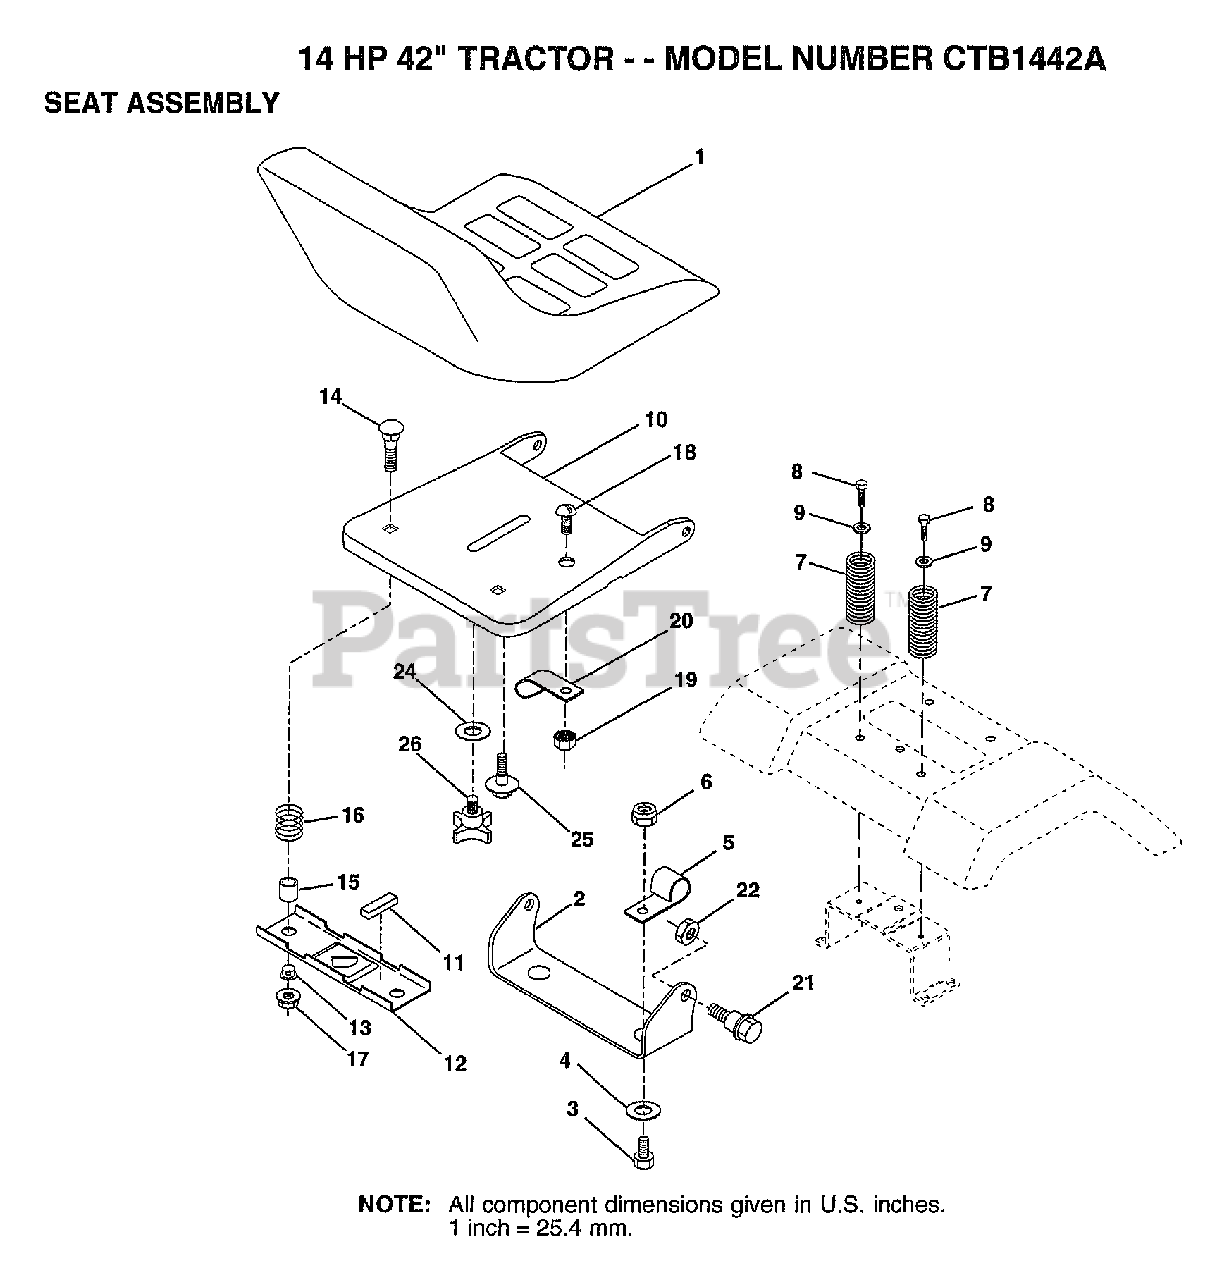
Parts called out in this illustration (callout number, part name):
4	WASHER PM
5	CLIP T
7	SPRING COMPRESSIO
8	SCREW GTV
9	WASHER
11	STRIP FORM
12	BRKT SWITCH
13	BUSHING
15	SPACER SPLIT
16	SPRING COMPRESSED
19	"NUT,KEPS"
24	WASHER
25	"BOLT,SHOULDER"
26	"KNOB 1/2"" YT"
